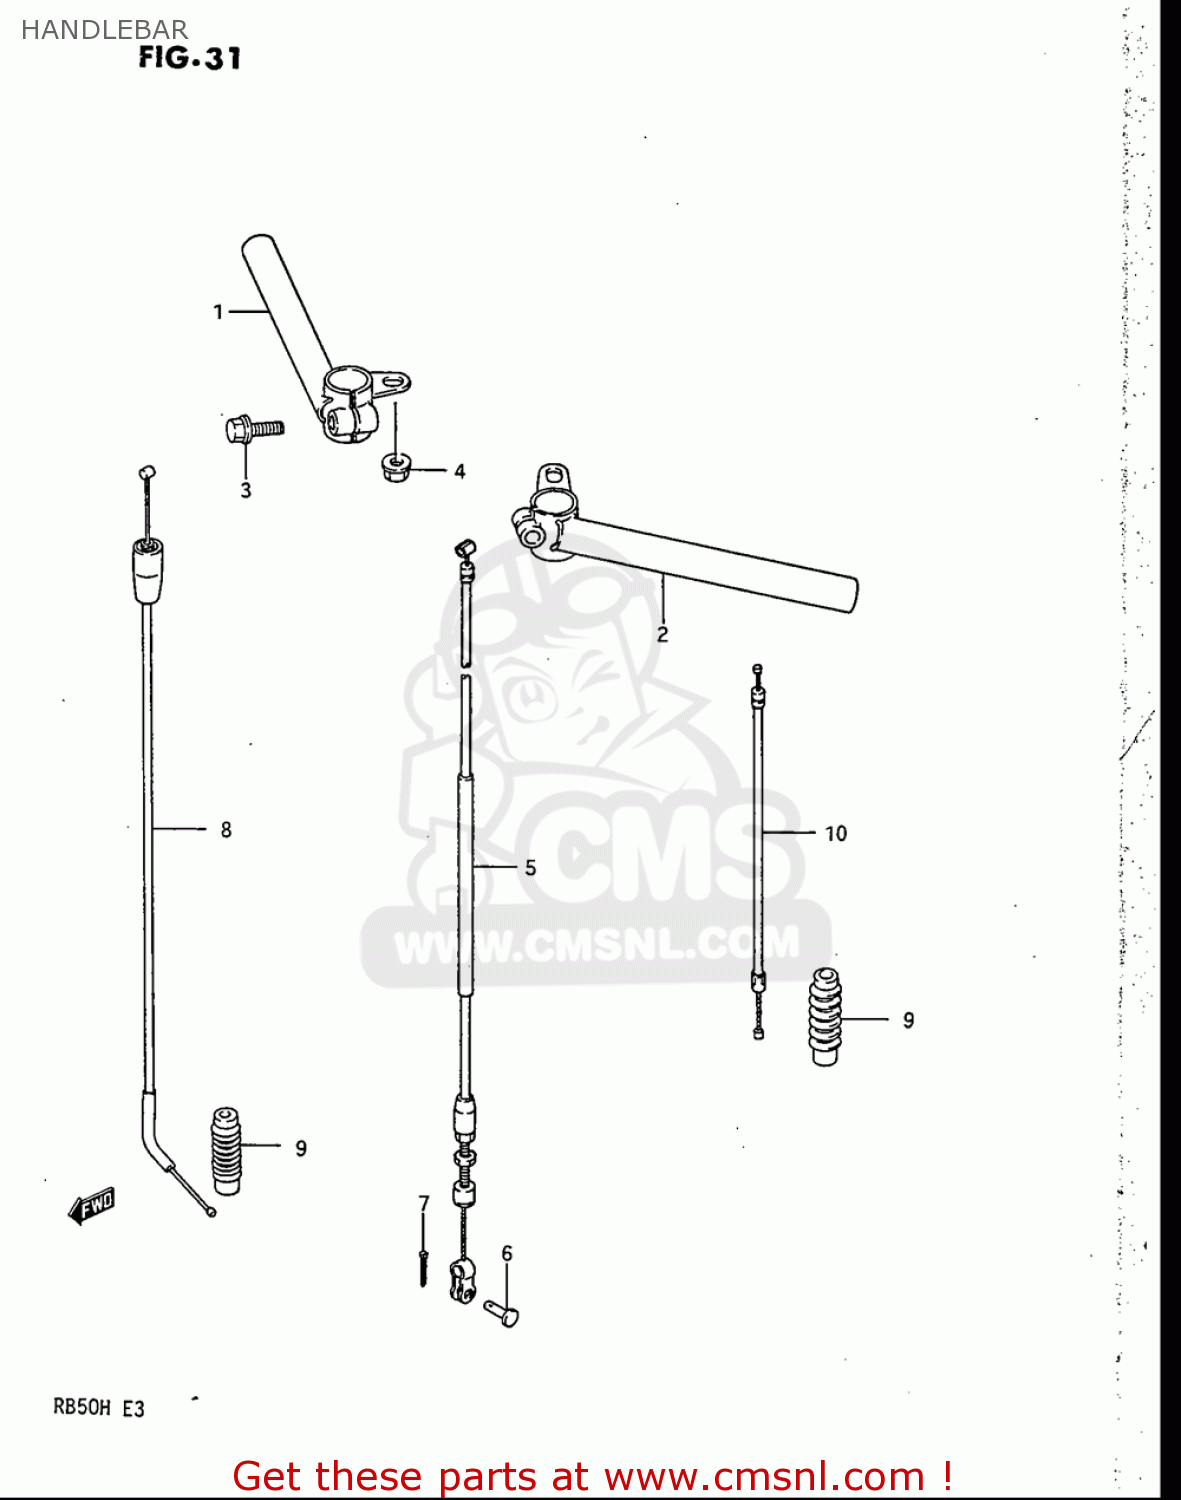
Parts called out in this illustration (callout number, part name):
3	BOLT
4	NUT
5	CABLE ASSY,CLUTCH
6	PIN(L:13)
7	PIN
8	CABLE ASSEMBLY,THROTTLE
